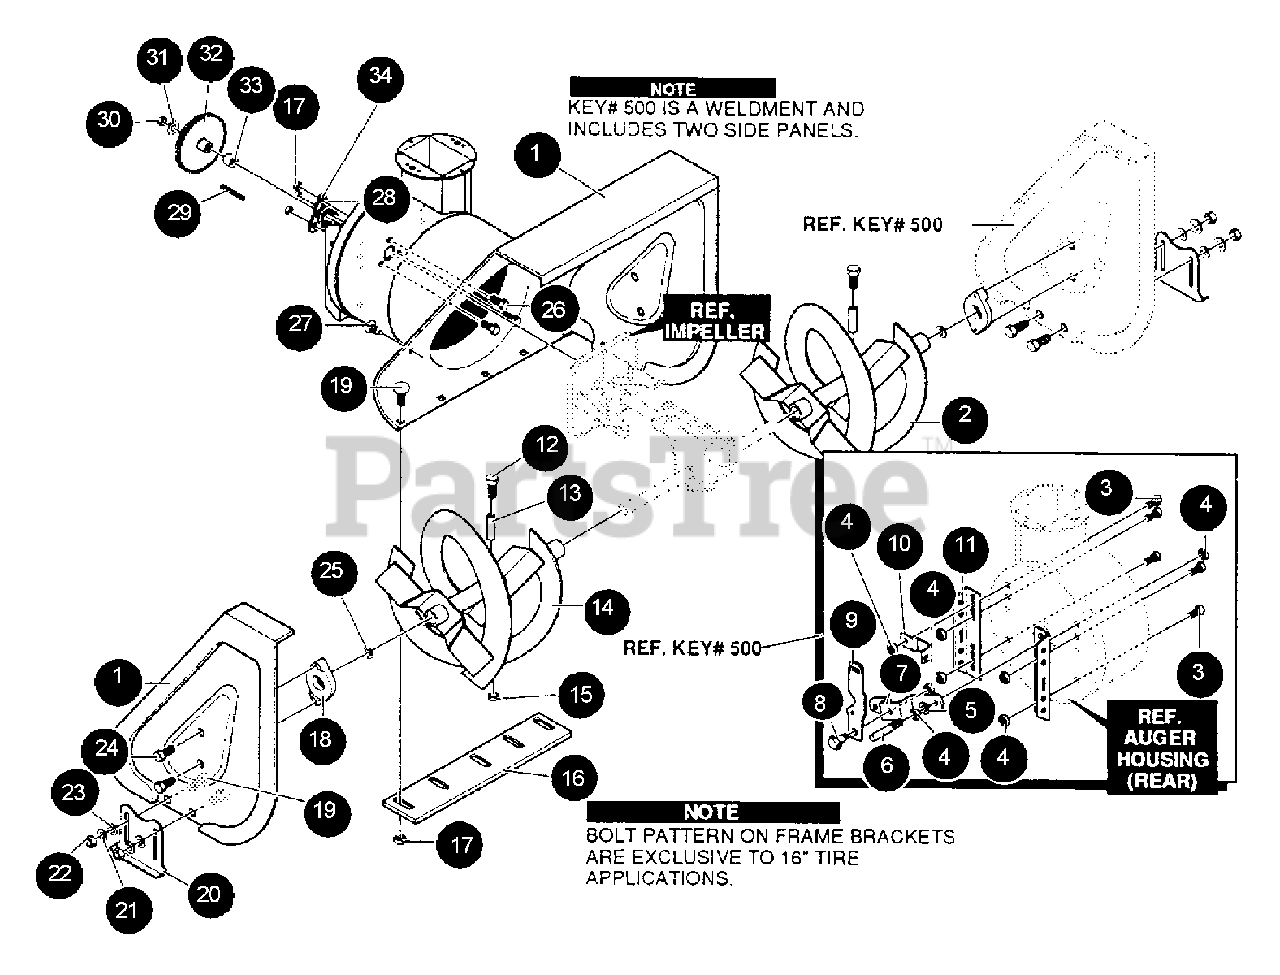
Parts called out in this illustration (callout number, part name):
1	AUGER INTAKE ASSY
2	AUGER ASSY - RIGHT
3	SCREW - 3/8-16 X 3/4"
4	NUT - 3/8-16
5	LOCKWASHER
6	STUD, BRAKE ARM
7	PLATE, CLUTCH
8	BOLT - 3/8-16
9	BRACKET, IDLER
10	BRACKET, CABLE
11	BRACKET, MOUNTING
12	SCREW - 1/4-20 X 1-3/4"
13	SPACER, SLEEVE .250X.47X.20
14	AUGER ASSY - RIGHT
15	NUT - 1/4-20
16	BLADE, SCRAPER
17	NUT - 5/16-18
18	BEARING, AUGER SHAFT
19	BOLT - 5/16-18 X 3/4"
20	SKID, HEIGHT ADJUST
21	LOCKWASHER
22	NUT - 5/16-18
23	WASHER
24	SCREW - 5/16-18 X 3/4"
25	WASHER - 1.00X1.31X.035
26	SCREW - 5/16-18 X 3/4"
27	PLUG, CHRISTMAS TREE
28	BEARING, BALL - 6203
29	KEY, SQUARE .18SQX88LG
30	LOCKNUT - 1/2-20
31	WASHER - .53X1.00X.063
32	PULLEY, V4L
33	SPACER, SLEEVE .675X1.00X.53
34	RETAINER, BEARING
